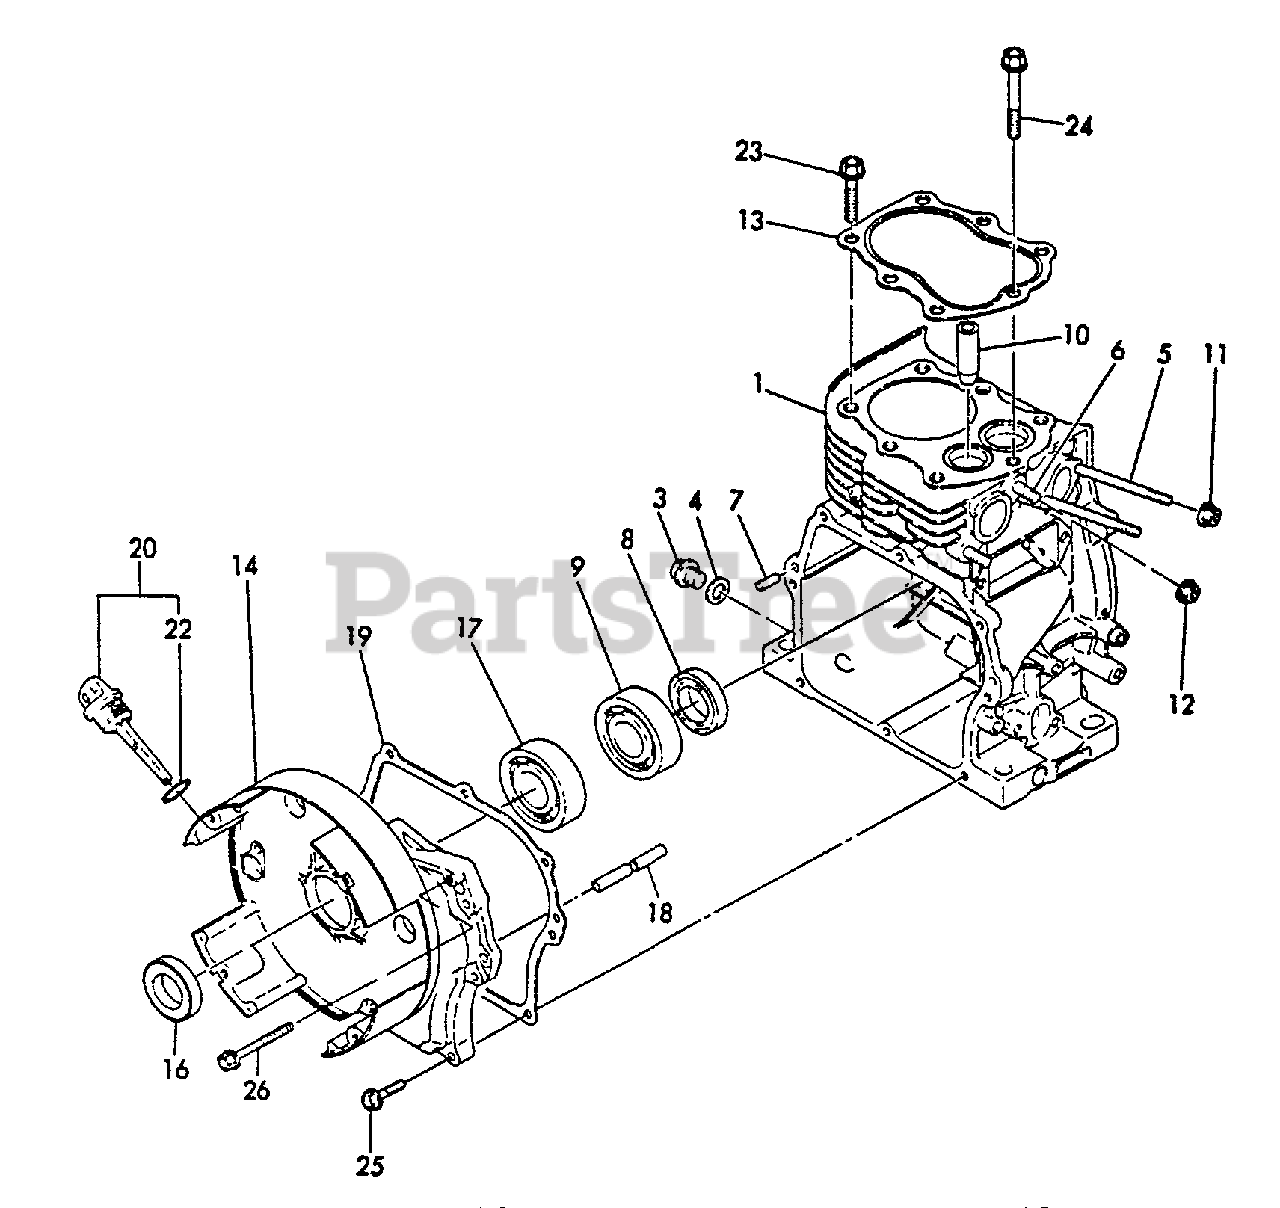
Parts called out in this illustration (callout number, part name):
1	CYLINDER BLOCK SET
3	PLUG, DRAIN
4	GASKET
5	BOLT - 6×70
6	STUD - 8×18 -- PLATED
7	PARALLEL PIN 6×16
8	SEAL, OIL
9	BEARING, BALL
10	GUIDE, VALVE
11	U-NUT M6
12	U-NUT M8
13	GASKET, CYLINDER
14	SIDE COVER ASSY
16	SEAL, OIL
17	BEARING, BALL
18	SHAFT, GOVERNOR
19	GASKET, SIDE COVER
20	CAP ASSY
22	O-RING 1A P-15.0
23	BOLT - 8×38
24	BOLT - 8×65
25	BOLT - 6×30
26	BOLT - 6×55
